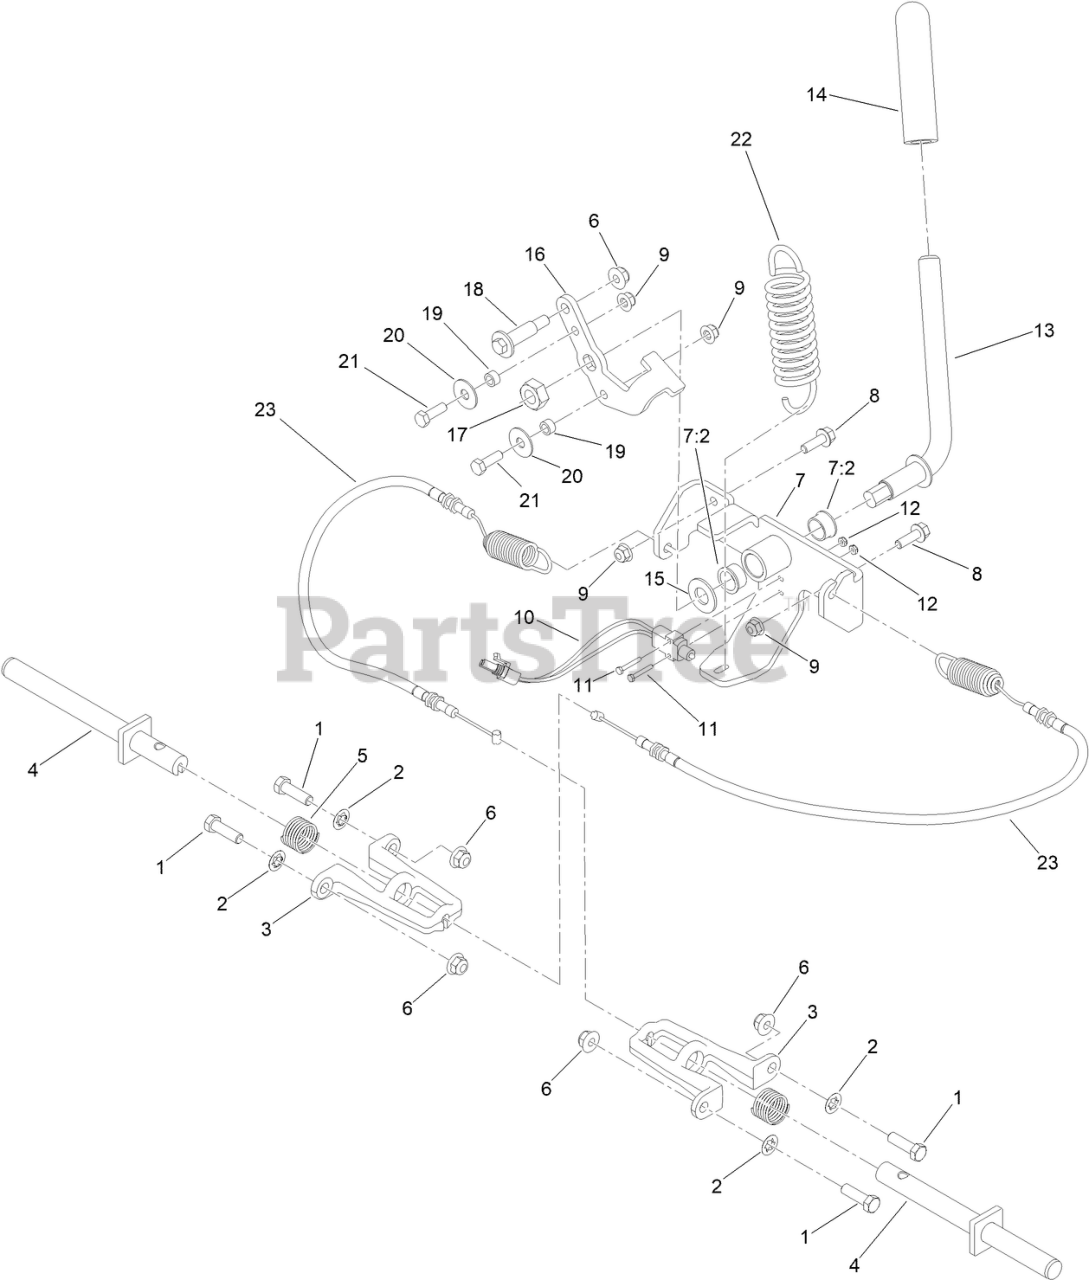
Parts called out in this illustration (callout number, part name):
1	SCREW-HH
2	NUT-PUSH
3	MOUNT-PIN [BLACK]
4	BRAKE ROD ASM
5	SPRING-COMPRESSION
6	NUT-HF, NI
7	BRACKET-BRAKE
7:2	BEARING-FLANGE
8	SCREW-HHF
9	NUT-HF, NI
10	SWITCH
11	SCREW
12	NUT-HEX
13	LEVER-BRAKE
14	GRIP-HANDLE
15	WASHER-FLAT
16	PLATE-BRAKE LINKAGE
17	NUT-LOCK, NI
18	BOLT-SHOULDER
19	SPACER-PIVOT, TILT
20	WASHER
21	SCREW-HH
22	SPRING-EXT
23	CABLE-BRAKE
